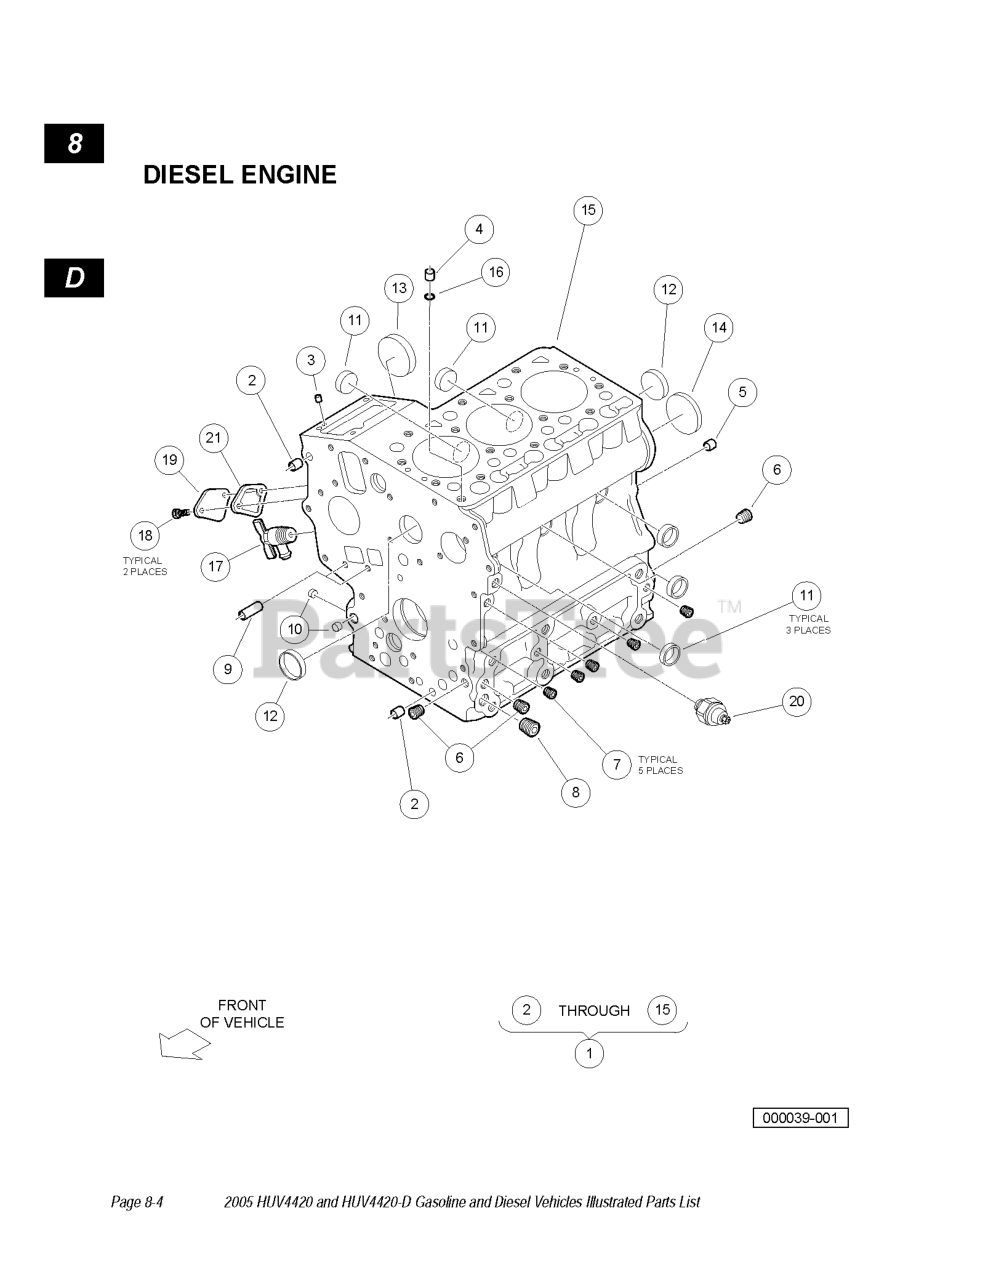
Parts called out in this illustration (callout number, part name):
1	ENGINE BLOCK
2	PIN, PIP, DIA 8 X 14
3	PIN, STRAIGHT, DIA 5 X 10
4	PIN, PIPE, DIA 7 X 14
5	PIN, STRAIGHT, DIA 8 X 16
6	PLUG, 1/8" NPT
7	PLUG, 3/32" NPT
8	PLUG, 1/4" NPT
9	PIN, PIPE, DIA 8 X 11
10	CAP, SEALING, SMALL
11	CAP, SEALING, MED
12	CAP, SEALING, LARGE
13	COVER, FUEL CAMSHAFT
14	PLUG, EXPANSION
16	O-RING, 8 X 7
17	ASSY COCK, DRAIN
18	BOLT, M6X1X20
19	PLATE, ENGINE BLOCK
20	SWITCH, OIL PRESSURE
21	GASKET, FUEL PUMP, D722
